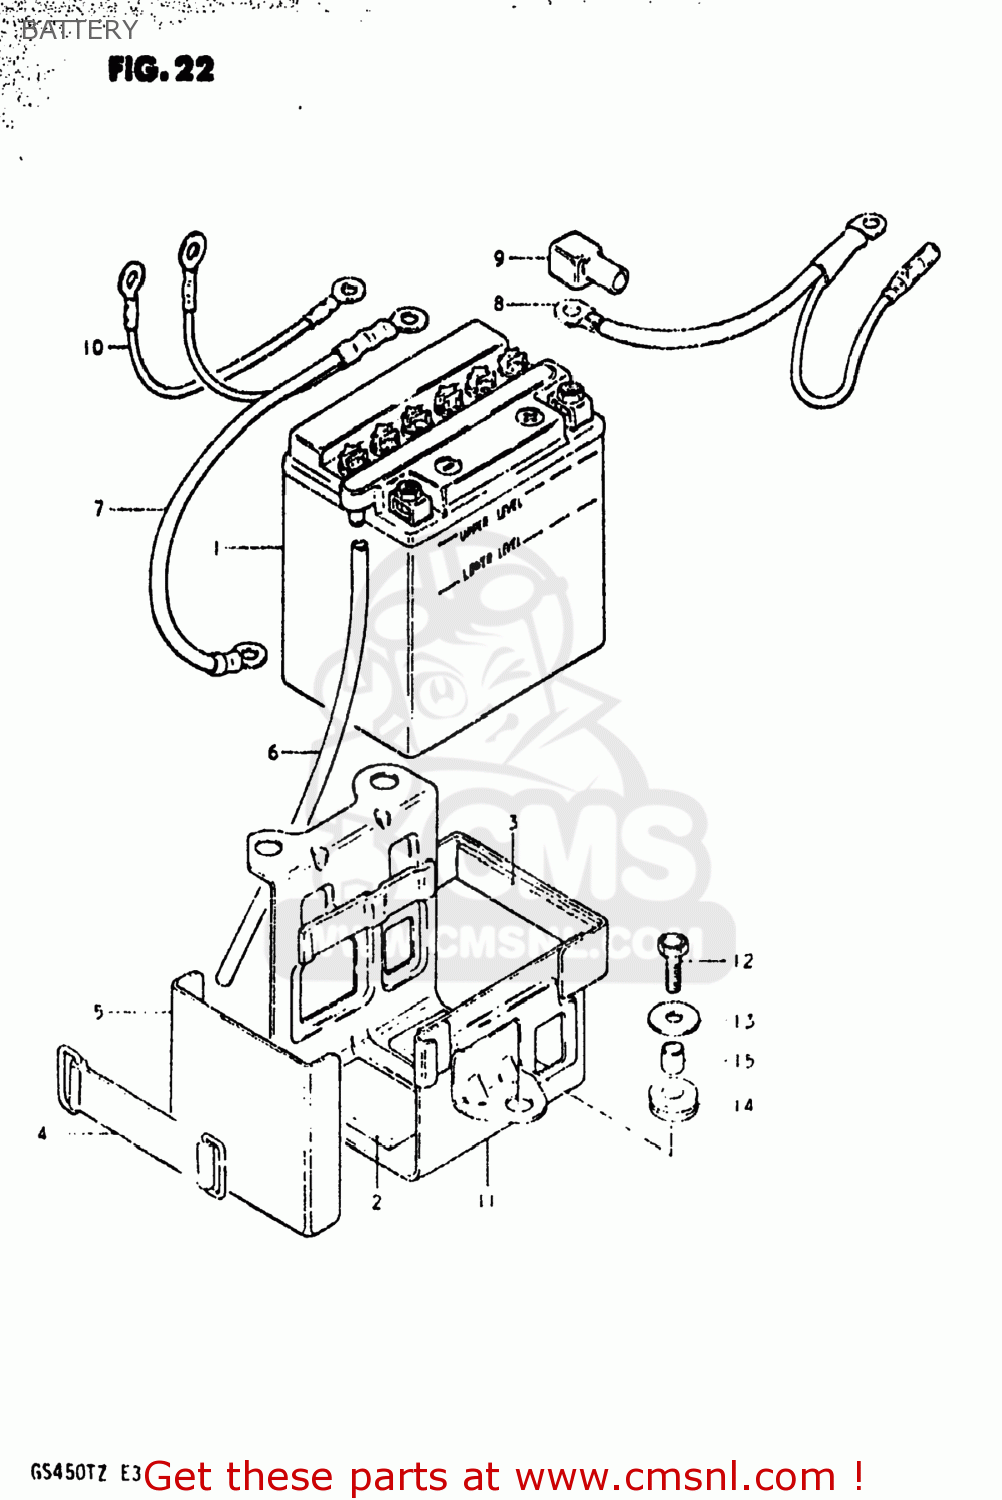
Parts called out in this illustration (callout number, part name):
1	BATTERY ASSY (12V)
2	CUSHION,BATTERY
3	PROTECTOR,20X9
4	BAND
5	COVER,BATTERY
6	HOSE,BATTERY EXHAUST
7	CORD,BATTERY MINUS
8	WIRE,BATTERY PLUS
9	CAP,TERMINAL
10	WIRE
11	HOLDER,BATTERY
12	BOLT
13	WASHER
14	CUSHION
15	SPACER (6.1X9X9)
